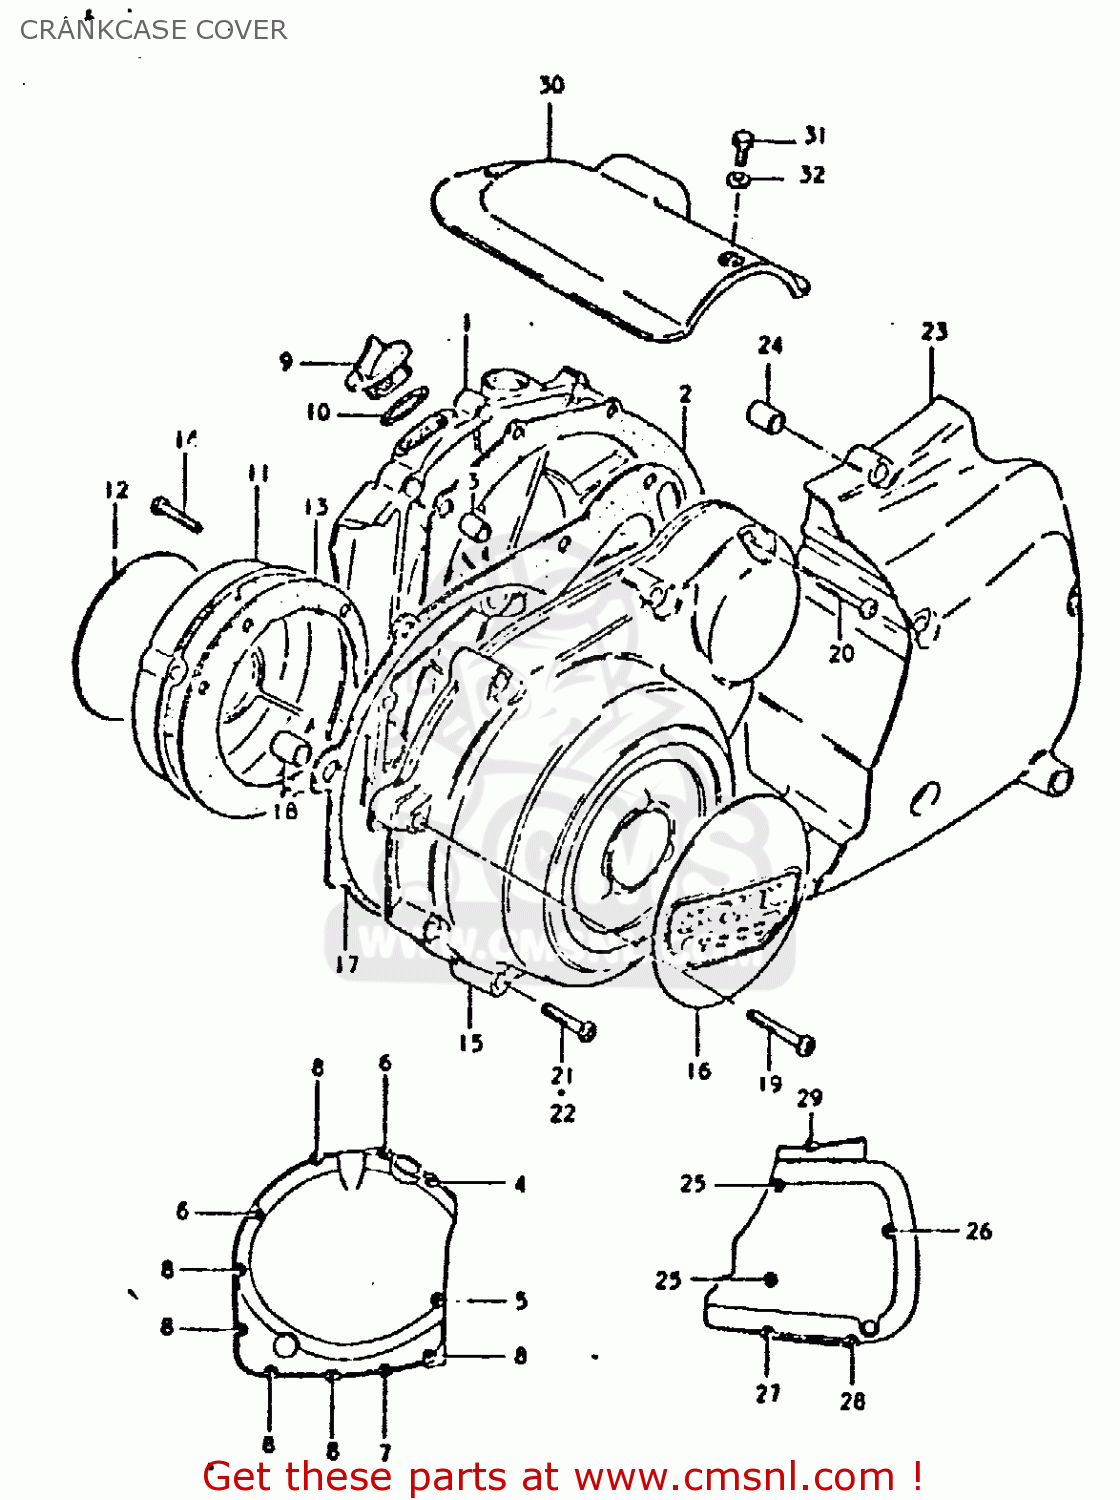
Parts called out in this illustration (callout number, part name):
1	COVER,CLUTCH
2	GASKET,CLUTCH COVER (MCA)
3	PIN
4	SCREW
5	SCREW (6X35)
6	SCREW 6X30
7	SCREW
8	SCREW
9	CAP
10	O RING(D:2.2,ID:32)
11	COVER,CONTACT BREAKER
12	EMBLEM
13	GASKET,CONTACT BREAKER COVER (NAS)
14	SCREW
15	COVER
16	EMBLEM,MAGNETO COVER
17	GASKET,MAGNETO COVER (MCA)
18	PIN
19	SCREW (6X45)
20	SCREW
21	SCREW (6X35)
22	SCREW 6X30
23	COVER,SPROCKET
24	PIN
25	SCREW (6*95)
26	SCREW 6X85
27	SCREW 6X70
28	SCREW
29	SCREW 6X30
30	COVER,STARTER MOTOR
31	BOLT
32	WASHER
